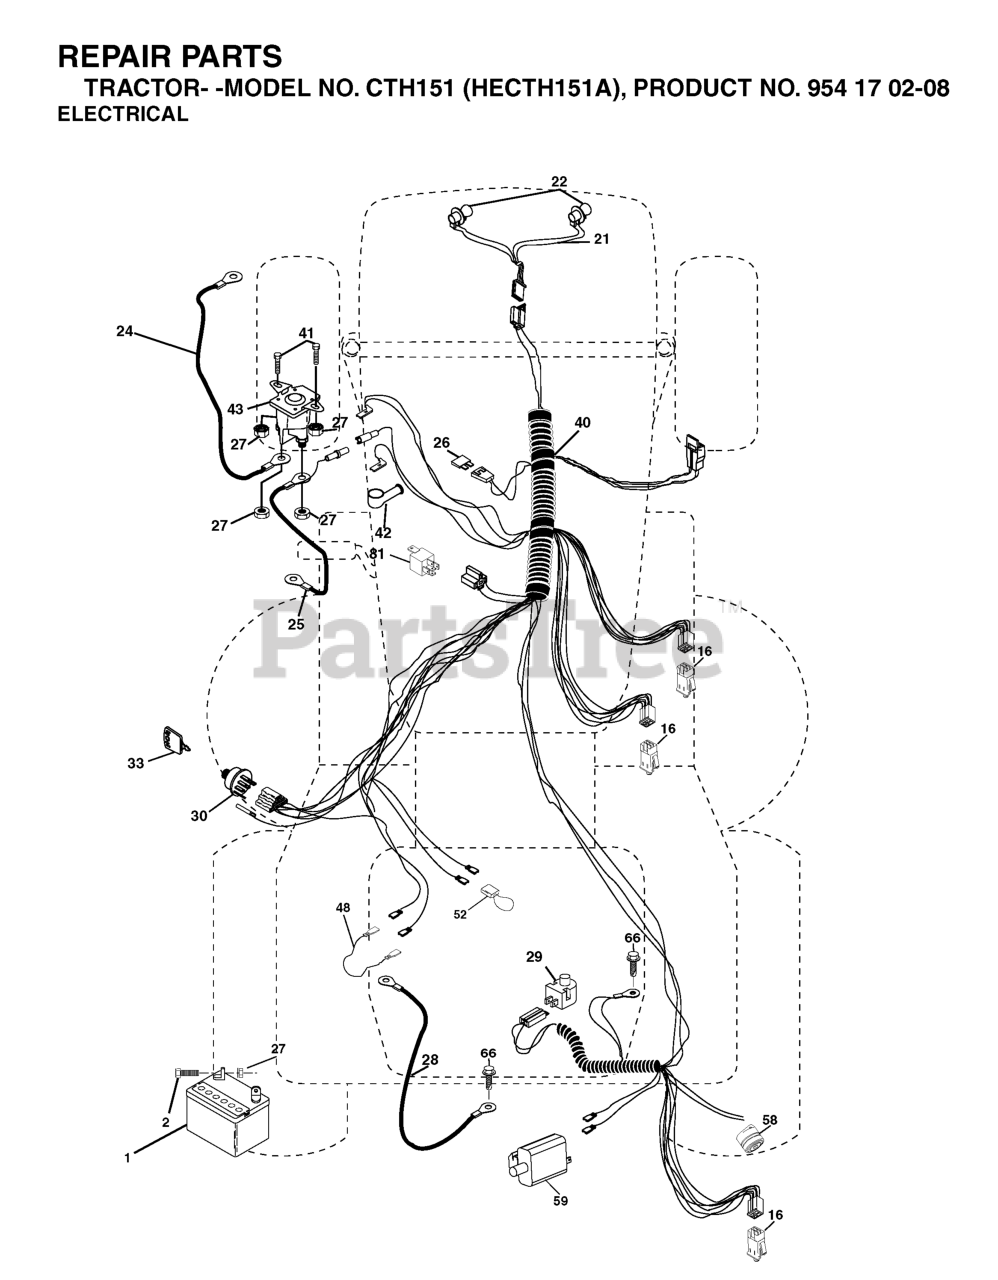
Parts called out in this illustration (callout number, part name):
1	BATTERY 12V .35 AMP
2	BOLT.HEX.1/4.X.3/4.DICHROMATE
16	SWITCH INTERLOOK PUSH-IN
21	HARNESS.W/LIGHT SOCKET
24	BATTERY CABLE GT
25	CABLE BATTERY
26	FUSE 20AMP
27	NUT
28	CABLE GROUND
29	PLUNGER SWITCH (COLOR:OLIVE)
30	IGNITION SWITCH
33	KEY MLD GEN DELTA
41	BOLT
42	TERMINAL COVER
43	SOLENOID
48	ADAPTER.AMMETER
52	WIRE PROTECTION LOOP
58	BUZZER
59	.WITCH.FULL BAGGER.INDICATOR
81	RELAY.ASSY.T
